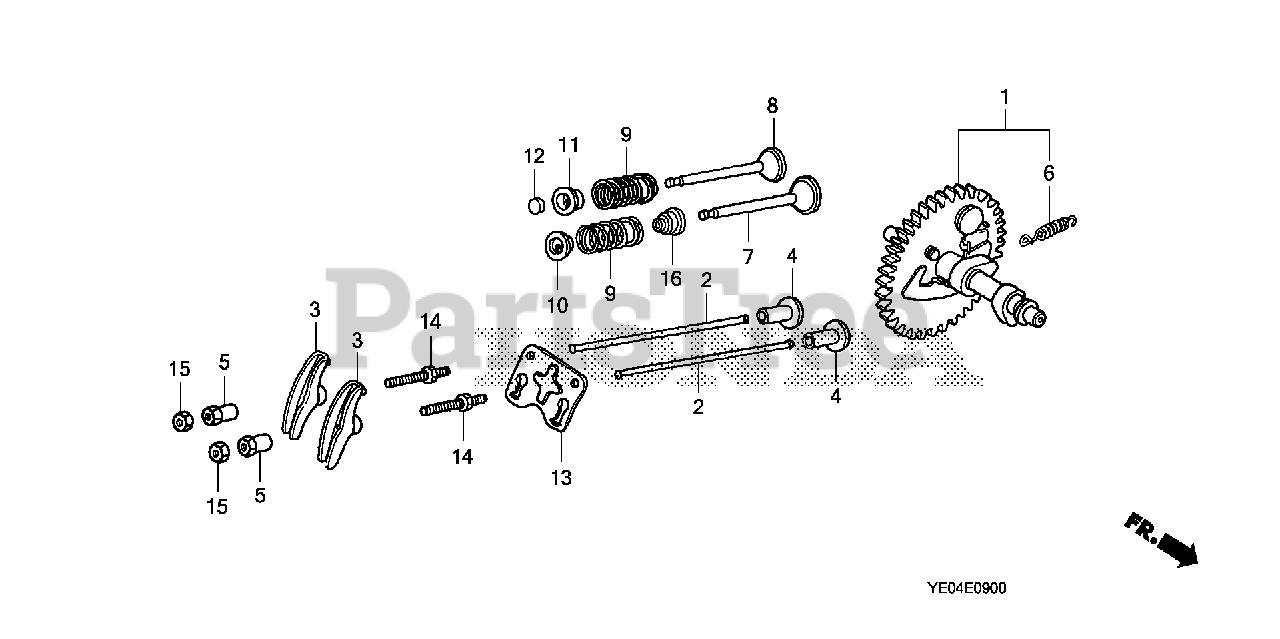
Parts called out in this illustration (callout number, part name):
1	CAMSHAFT ASSY.
3	ARM, VALVE ROCKER
4	LIFTER, VALVE
5	PIVOT, ROCKER ARM
6	SPRING, WEIGHT RETURN
7	VALVE, IN.
8	VALVE, EX.
9	SPRING, VALVE
10	RETAINER, IN. VALVE SPRING
10	RETAINER, VALVE SPRING (EXHAUST SIDE)
11	RETAINER, IN. VALVE SPRING
11	RETAINER, VALVE SPRING (EXHAUST SIDE)
13	PLATE, PUSH ROD GUIDE
14	BOLT, PIVOT (8MM)
15	NUT, PIVOT ADJ.
16	SEAL, VALVE STEM
